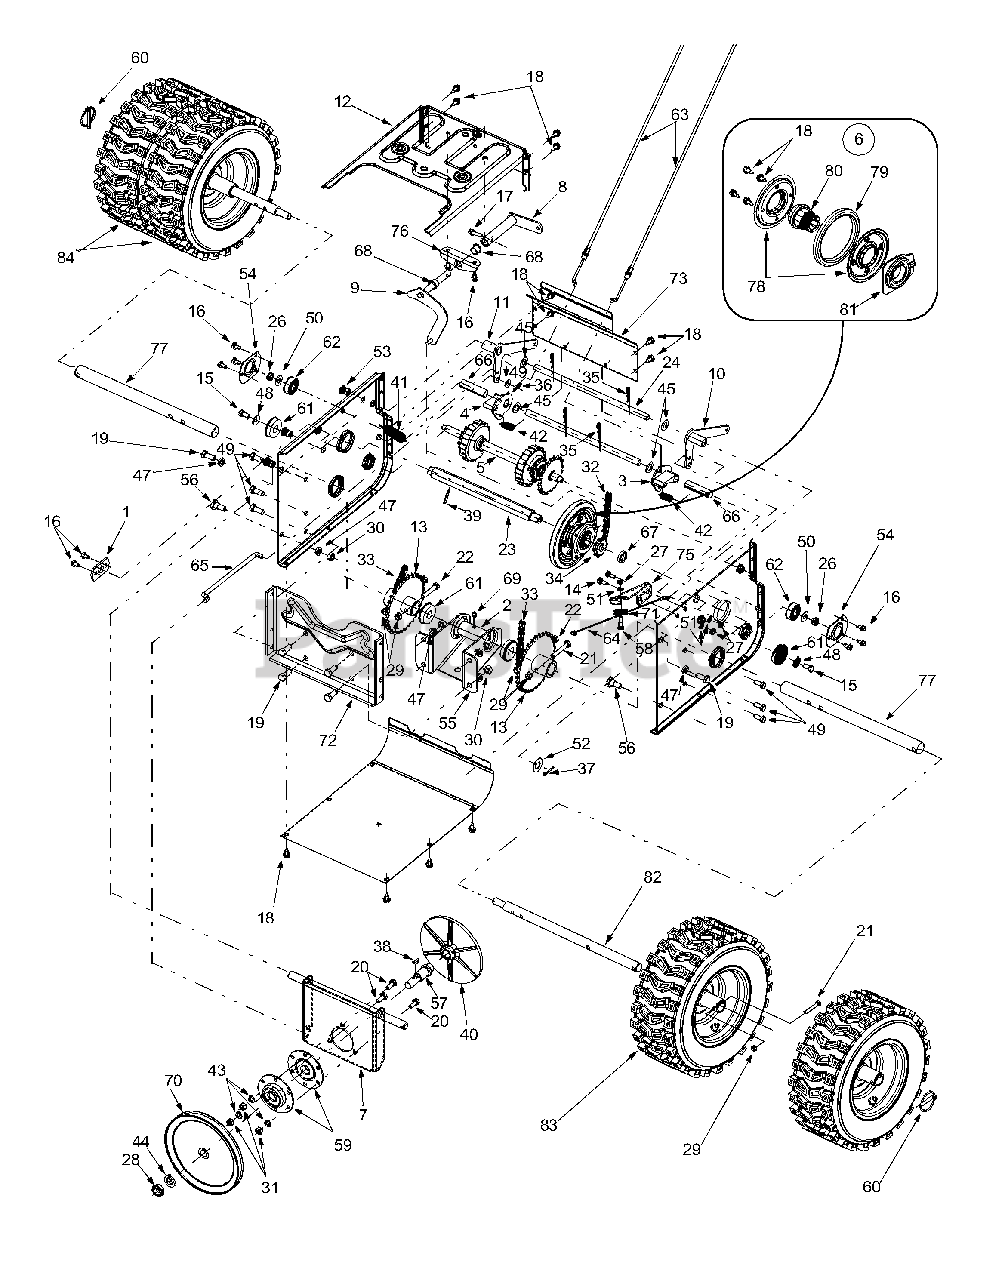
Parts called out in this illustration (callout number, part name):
1	Pivot Support Bracket
2	Spacer, .6725 x 1.125 x 2.485
3	Dogg Assembly LH
4	Dogg Assembly RH
5	Shaft Assembly
6	Friction Wheel Assembly
9	Shift Rod Assembly
10	Auger Actuator Bracket Assy.
14	Hex Screw, 1/4-28 x .625"
15	Hex Screw, 5/16-18 x .625"
16	Self-tapping Screw, 1/4-20 x .5
17	Self-tapping Screw, 1/4-20 x 1"
18	Self-tapping Screw, 1/4-20 x .625"
19	Hex Screw 3/8-16 x .880"
20	Hex Screw 5/16-18 x .75"
21	Hex Screw 5/16-18 x 2"
22	Hex Screw 5/16-18 x 1.75"
23	Hex Shaft, Drive
24	Actuator Shaft
27	Hex Nut 1/4-28
28	Jam Lock Nut
29	Hex Lock Nut
30	Hex Nut 3/8-16
31	Hex Nut 5/16-18
35	Hairpin Clip
36	Hairpin Clip
37	Cotter Pin
38	Key
39	Roll Pin
40	Drive Plate
41	Extension Spring
42	Extension Spring
43	Lock Washer 5/16
44	Lock Washer 5/8
45	Flat Washer
47	Lock Washer
48	Bell Washer
49	Self-tapping Screw, 5/16-18 x .625
50	Flat Washer
51	Lock Washer
52	Flat Washer
53	Nut Insert, 3/8-16
54	Bearing Retainer Bracket
56	Shoulder Screw
57	Spindle, Drive Plate
58	Shoulder Screw 1/4-28 x .375"
59	Bearing Housing Assembly
61	Ball Bearing
62	Ball Bearing
63	Steer Cable
64	Auger Idler Cable
65	Drive Clutch Rod
66	Split Spacer
67	Spacer
68	Flange Bearing
69	Lube Fitting, 3/16
70	Drive Pulley
71	Roller Cable
78	Friction Plate
79	Friction Wheel Rubber
80	Friction Wheel Hub
81	Friction Wheel Bearing
82	Wheel Axle
83	Wheel Assembly, LH
84	Wheel Assembly, RH
